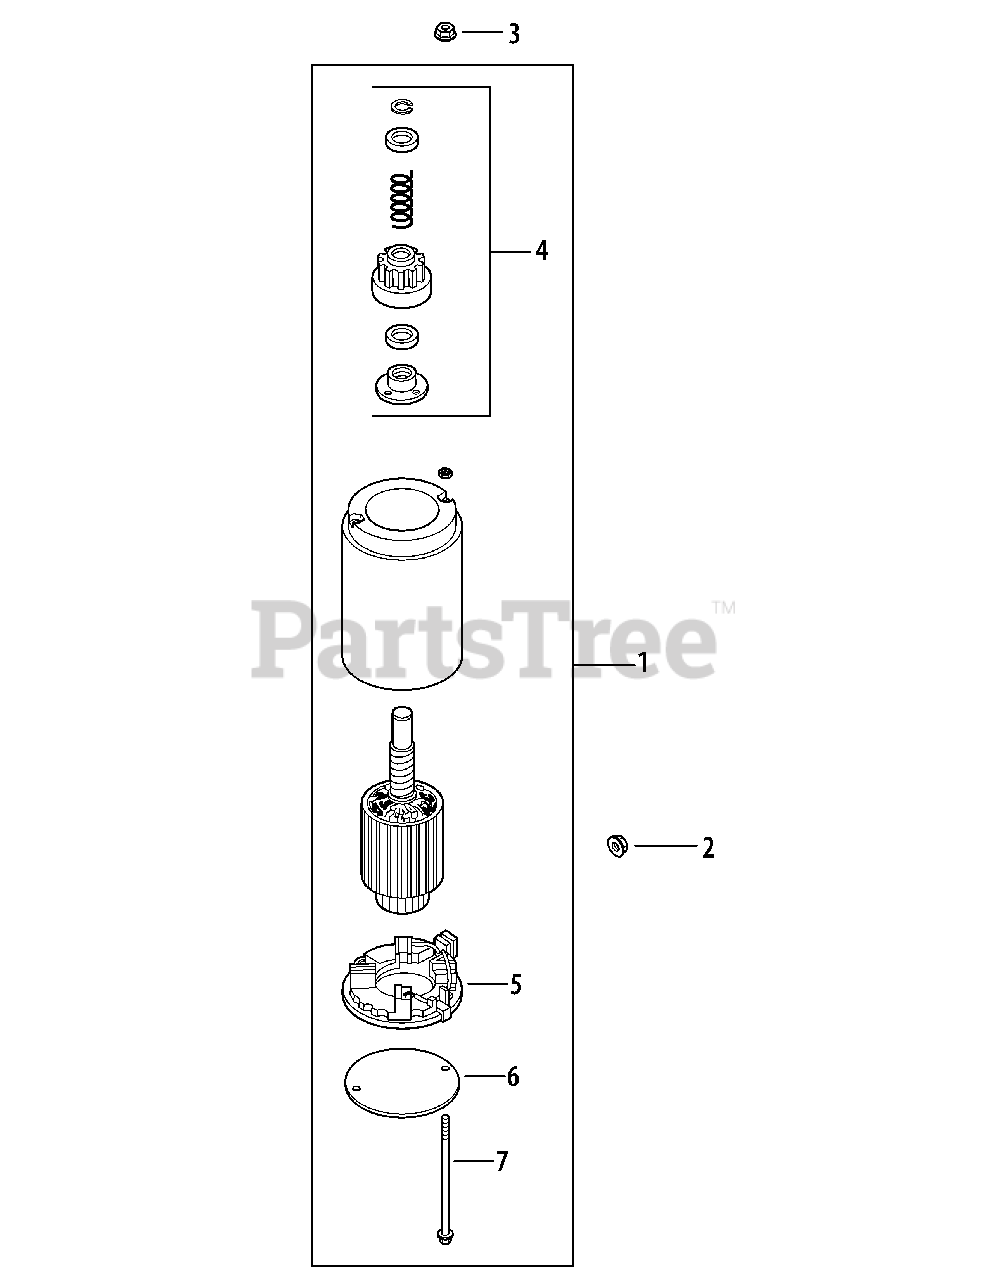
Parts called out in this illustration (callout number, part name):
1	Starter Assembly (Inc. 4-7)
3	Free Spinning Flg. Nut, #10-24
4	Drive Kit (J.E.)
6	Drive End Cap (J.E.)
